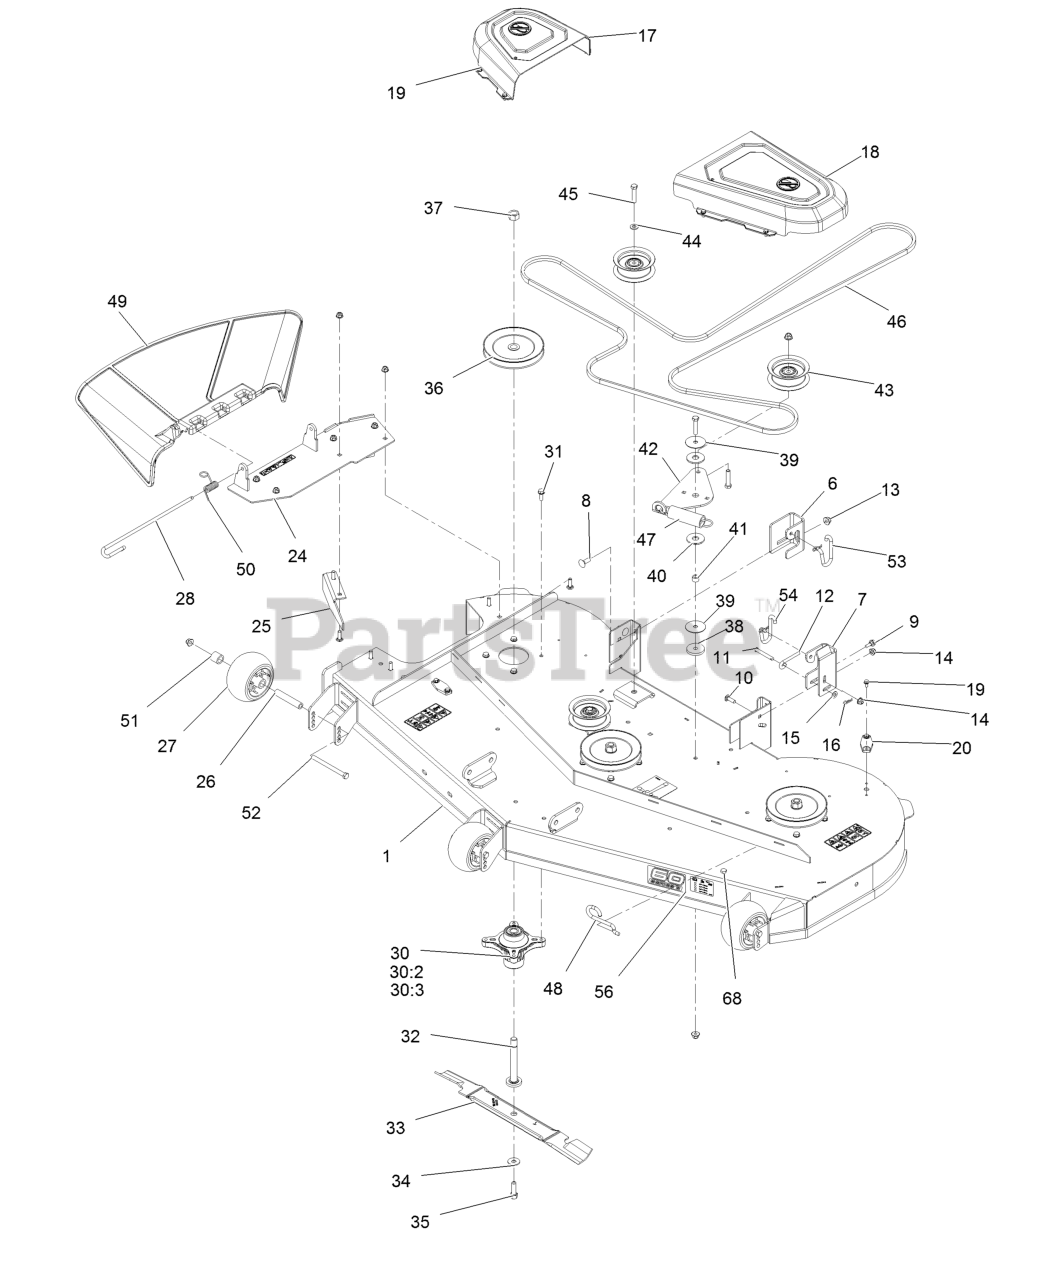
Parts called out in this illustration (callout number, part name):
1	60 INCH DECK AND DECAL ASM
6	BRACKET-HANGER, RH
7	BRACKET-HANGER, LH
8	BOLT-CARR
9	SCREW-SHOULDER,HWH
10	SCREW-CARR
11	PIN-CLEVIS
12	ROD-LEVEL, DECK
13	NUT-HF, NI
14	NUT-HF, NI
15	WASHER-PLAIN
16	PIN-COTTER
17	COVER-BELT, RH
18	COVER-BELT, LH
19	SCREW-HWH
20	COVER-WASHOUT PORT
24	PIVOT-DEFLECTOR
25	BAFFLE-CUTOFF
26	TUBE-SPANNER
27	ROLLER-SCALP, ANTI
28	PIN-CHUTE
30	SPINDLE ASM
30:3	BEARING-BALL
31	SCREW-TAPTITE
32	SHAFT-SPINDLE
33	BLADE-HI FLOW, 20.5 INCH
34	WASHER-BELLEVILLE
35	SCREW-HH
37	NUT-HEX
38	WASHER-PLAIN
40	WASHER-FRICTION, COMPOSIT
42	ARM-IDLER
43	PULLEY-IDLER, FLAT
44	WASHER-FLAT
45	SCREW-HH
46	BELT
47	SPRING-EXTENSION
48	HOOK-RETURN, SPRING
49	DEFLECTOR-DISCHARGE
50	SPRING-TORSION
51	SPACER-AXLE, REAR
52	SCREW-HH
53	LINK-RETENTION, DECK (RH)
54	LINK-RETENTION, DECK (LH)
56	DECAL-SERIES 2 60
68	SCREW-HH
